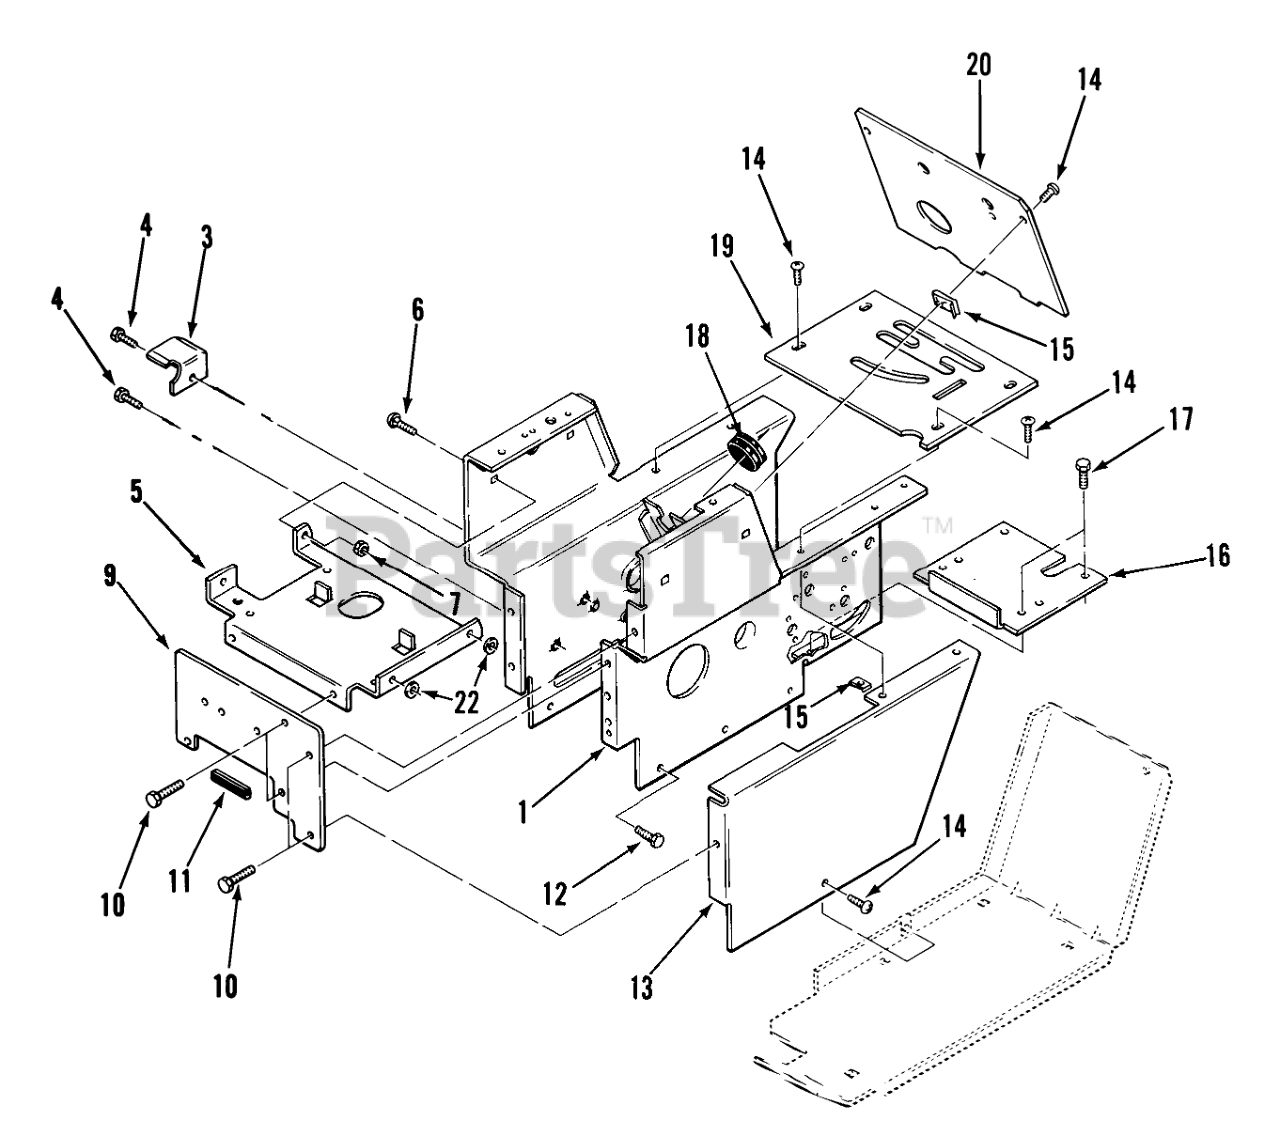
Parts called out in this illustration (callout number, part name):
1	Hoodstand
3	Belt Bracket
4	SCREW
5	Battery Support Bracket
6	CARRIAGE BOLT -4
7	Nut
9	Front Plate
10	SCREW
11	EDGE TRIM 2" 102896
12	SCREW
13	Side Cover LH
14	Screw
16	Cover-Dust
17	SCREW
18	GROMMET
19	Shift Cover Plate
20	PLATE-HOODSTAND REAR
20	Ammeter Plate
22	WASHER 5/16 SAE
